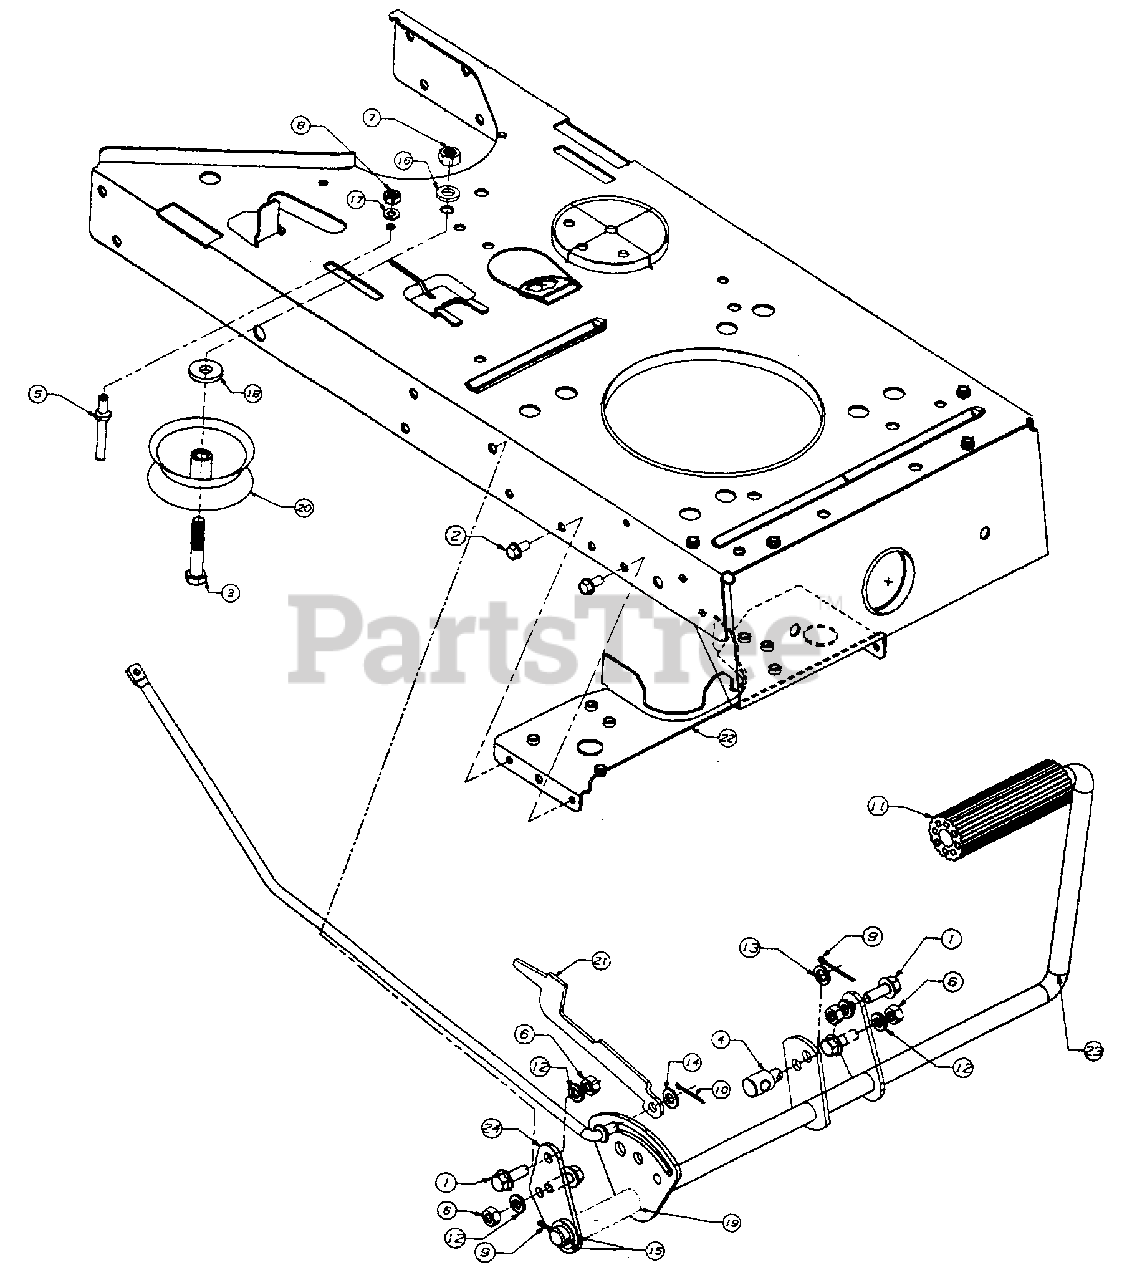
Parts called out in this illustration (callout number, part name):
1	Hex Flange Bolt 5/16-18 x .875" Lg.
2	Hex Wash. Hd. TT-Tap Scr. 1/4-20 x .5" Lg.
3	Hex Bolt 3/8-16 x 2" Lg.
4	Ferrule 3/8-24 Thd.
5	Belt Guard Pin
6	Hex Nut 5/16-18 Thd.
7	Hex Nut 3/8-16 Thd.
8	Hex Nut 1/4-20 Thd.
9	Cotter Pin 1/8" Dia. x 1.25" Lg.
10	Cotter Pin 3/32" Dia. x 1" Lg.
11	Foot Pad
12	L-Wash. 5/16" I.D.
13	Fl-Wash. .385" I.D. x .62" O.D.
14	Fl-Wash. .33" I.D. x .63" O.D.
15	Fl-Wash. .63" I.D. x .93" O.D.
16	L-Wash. 3/8" I.D.
17	L-Wash. 1/4" I.D.
18	Fl-Wash. .385" I.D. x 1" O.D.
19	Spacer .64" I.D. x 2.63" Lg.
20	Fl-Idler 2.75" O.D.
21	Foot Pedal Switch Brkt.
